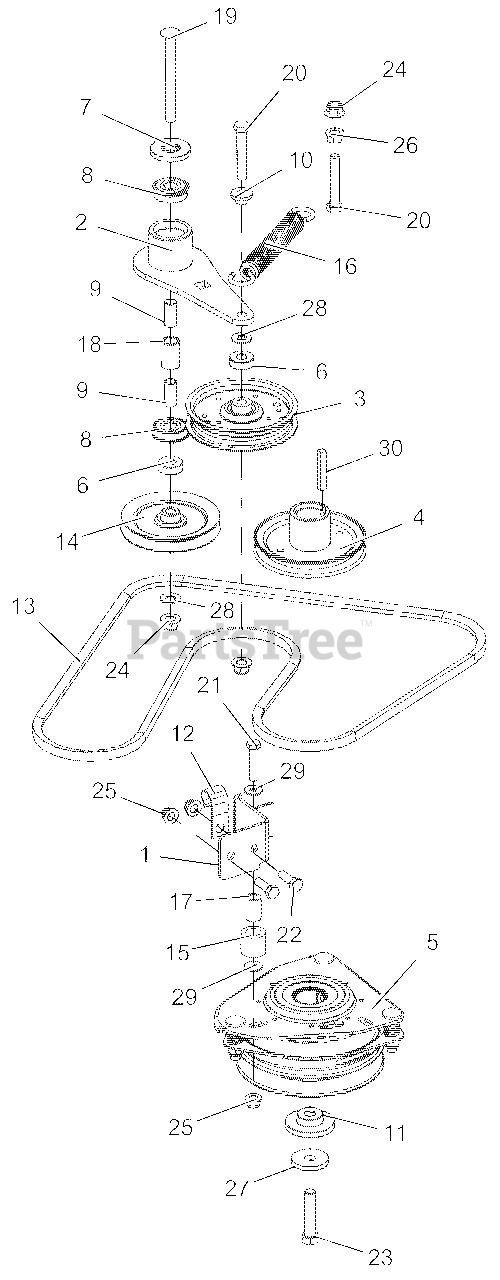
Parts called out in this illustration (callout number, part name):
1	WLDMT, CLUTCH STOP-BLACK
2	WLDMT, IDLER ARM GROUND DRIVE
3	ASM, IDLER 4"
4	SHEAVE, ENGINE 4.50 X 1.127-BLACK
5	CLUTCH, ELEC OGURA GT1A-AR03
6	SPCR, .375 X 1.00 X .342
7	SPACER, IDLER ARM
8	BRG, BALL .501 X 1.38 X .438 SEALED
9	BSHG, SLV .385 X .500 X 1.045
10	BSHG, FLG .385 X .500 X .875 X .406
11	BSHG, -FLG .469 x 1.06 x .574 x 2.0
13	BELT, V- A COGGED
14	SHEAVE, IDLER -V .38 x 4.00
15	BUMPER, RUBBER .62 X 1.0 X .88 LG
16	SPRG, EXTENSION
17	BUSH.,S.391X.622X.95 ST REV A
18	SPACER, .510 X .750 X 1.148
19	BLT-RHDSSQNK .38-16X4.00 G5YZ
20	BLT-HEX .38-16X2.25 GR5 YWZC
21	BLT-HEX .31-18X1.50 GR5 YWZC
22	BLT-HEX .31-18X1.00 GR5 YWZC
23	BLT-HEX .44-20X2.00 GR8 YWZC NYTORQ
24	NUT-LK-NYL-FLG .38-16 YWZC
25	NUT-LK-NYL-FLG .31-18 YWZC
26	@NUT-SPNLK-FLG .375-16 YWZC
27	WSHR, 7/16" SPRING DISC
28	WSHR-FL-STL.406X.812X.065 YWZ
29	WSHR-FL-STL.312X.734X.065 YWZ
30	KEY-STR .25X1.75X.25
